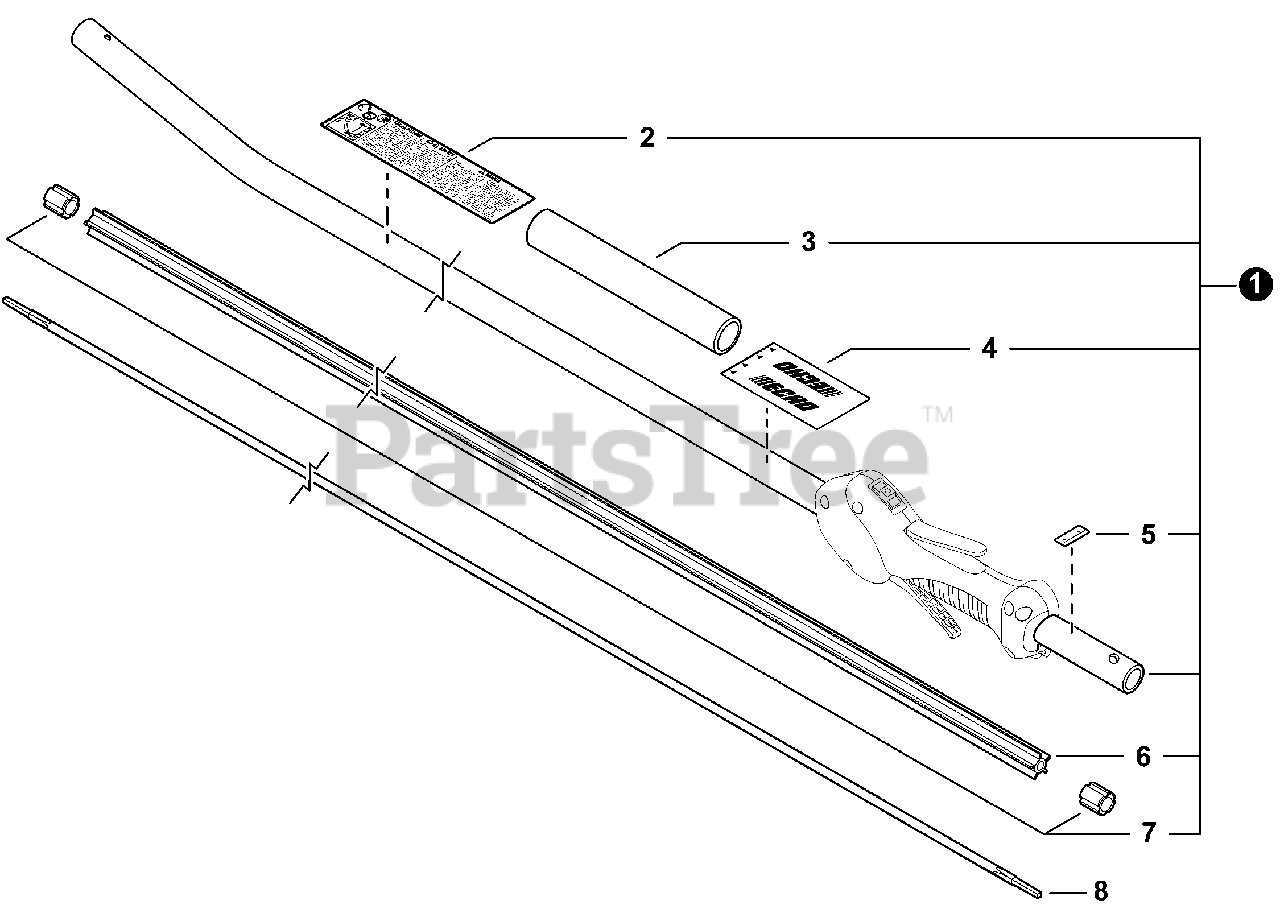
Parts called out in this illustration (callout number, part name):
1	MAIN PIPE ASSY
2	LABEL, CAUTION
3	GRIP, HANDLE
4	LABEL, HANDLE LOCATION
5	LABEL - ALIGNMENT
6	LINER - FLEXIBLE
8	DRIVESHAFT - FLEXIBLE
